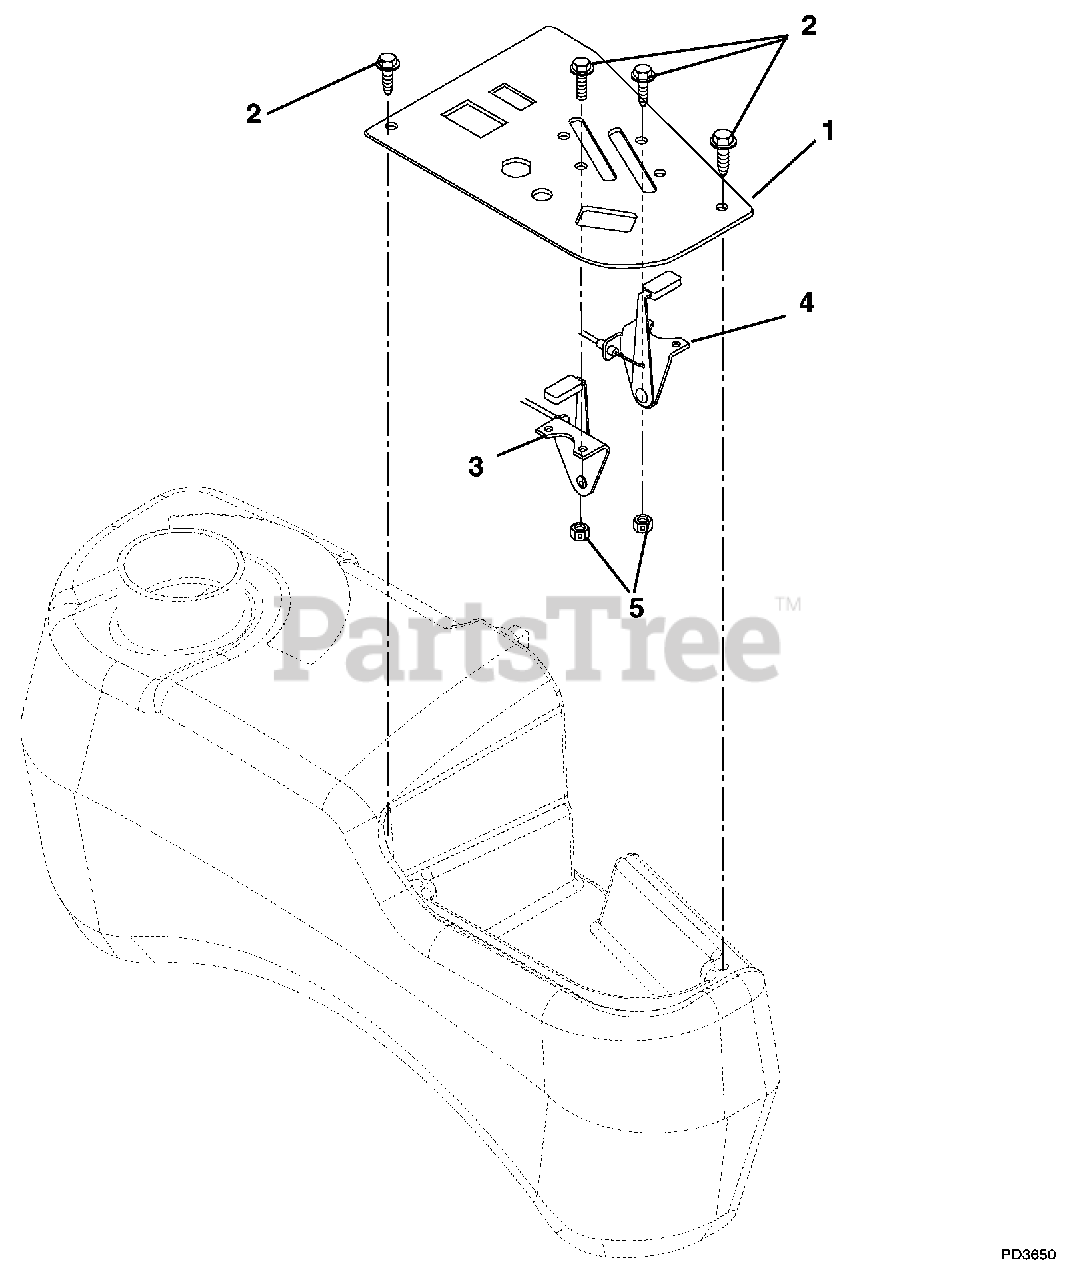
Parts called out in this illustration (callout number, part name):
1	Panel, Control
2	Screw, Machine 10-24 x .50 Hex Washer Head
3	Cable, Throttle
4	Cable, Choke, Kohler (054, 055)
4	Cable, Choke, Kawasaki (042, 043, 044, 051, 310, 311)
5	Nut, Locking Nylon 10-24 With Insert
